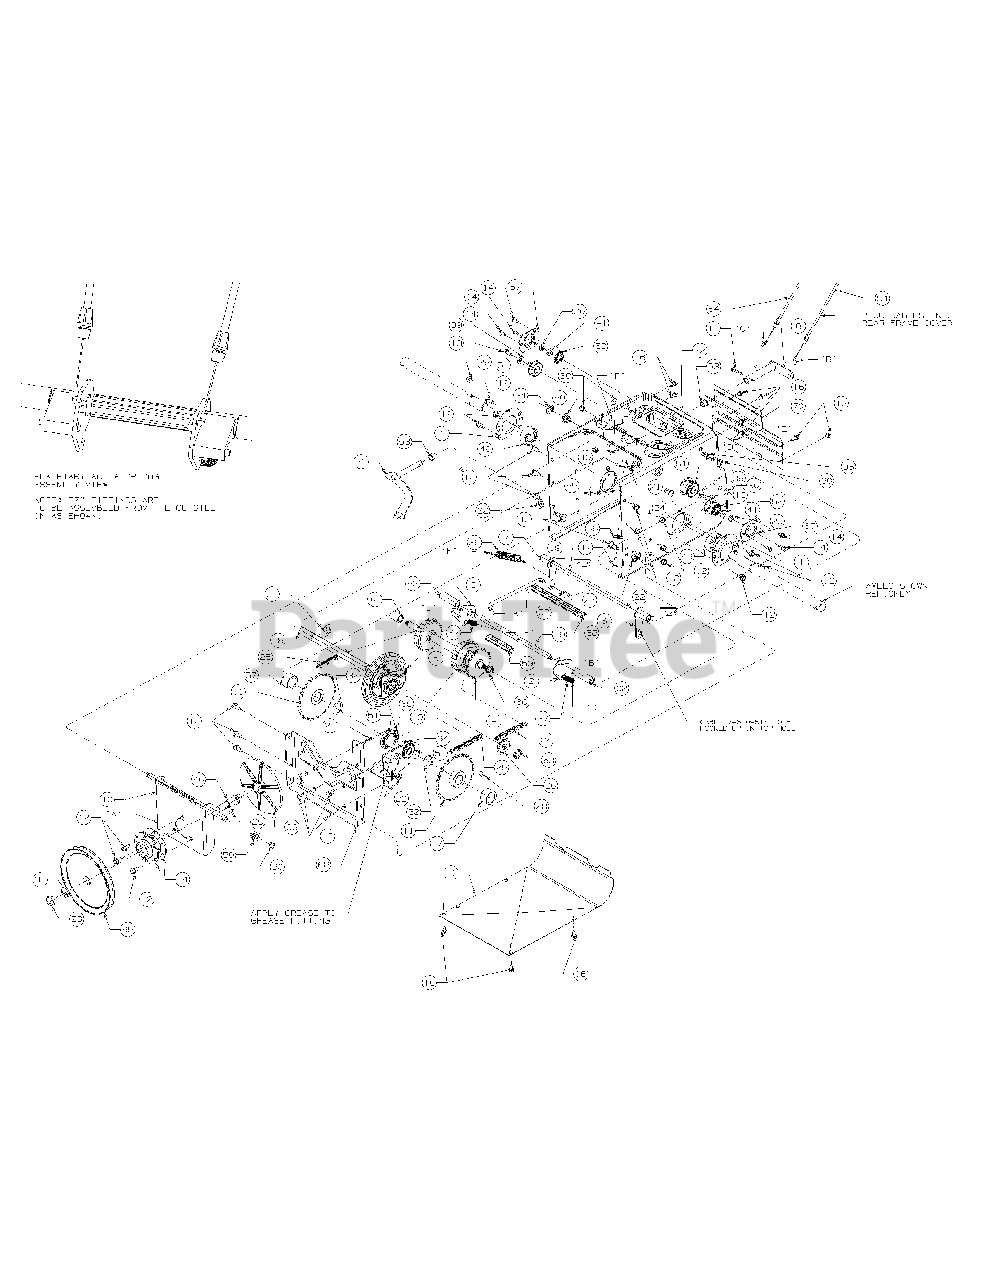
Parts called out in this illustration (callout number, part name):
1	Bearing Housing
2	Dogg Assy-Lft D
3	Dogg Assy-Rgt D
4	Shaft Asm:Drive
5	Wheel Asm-Frict
6	Bracket-Au
7	Bracket-Au
8	Arm Assy-Sh
9	Rod-Shift Asm
10	Bracket Asm
11	Sprocket Asm:32T
13	Screw-Hex 5/16-18
14	Bearing Housing Assy
14	Hex Washer Screw 1/4-20 x .625
15	Screw-Tap 1/4-20
16	Screw Hex.Wash.Hd
17	Screw-Hex Cap 3/8
18	Shaft-Hex Drive
19	Shaft:Actr
20	Nut-Hex Ins
21	Nut-Hex 1/4-28
22	Nut-Flange Lk.Nylo
23	Nut-Hex Jam Lock
24	#41 Chain 1/2 Pitch
25	#420 Chain 1/2 Pitch
26	Sprocket
27	Pin:Cot:.072 Dia
28	Key-Woodruff #91
29	Key-3/16 X 5/8
30	#41 Chain 1/2 Pitch
31	Ring-Retaining-E T
32	Ring-"E" 1.50 Od
33	Plate-Alum Drive
34	Cap-Push
35	Rivet-Nut
36	Spring-Idler Ext
37	Spring-Extension
38	Washer-Lock 5/8
39	Washer-Bell .337 X
40	Washer-Lock
41	Washer-Thrust
42	Grease
43	Grease
44	Grease Fitting
45	Screw-Shld .498 Di
46	Spindle-Drive Plt
47	Screw-1/4-28 X .32
49	Bearing-Self Al
50	Bearing-Hex Flange
51	Ball Bearing
52	Bearing-Ball
53	Bushing-Flange
54	Cable-Wheel Steeri
55	Cable-Auger Idl
56	Rod-Drive Clutch
57	Spacer
58	Spacer
59	Spacer
60	Spacer-Strbl Drv Sha
61	Spacer-Strbl Drv Sha
62	Spacer-Split Shld
63	Spacer
64	Spacer:.6725Id X
65	Pulley
66	Roller-Cable Guide
67	Bracket-Retaining Bearing
68	Bracket-Sup
69	Bracket-Sup
70	Cover:Upper Frame:
71	Cover:Frame:Lower
72	Frame-Trans 900
